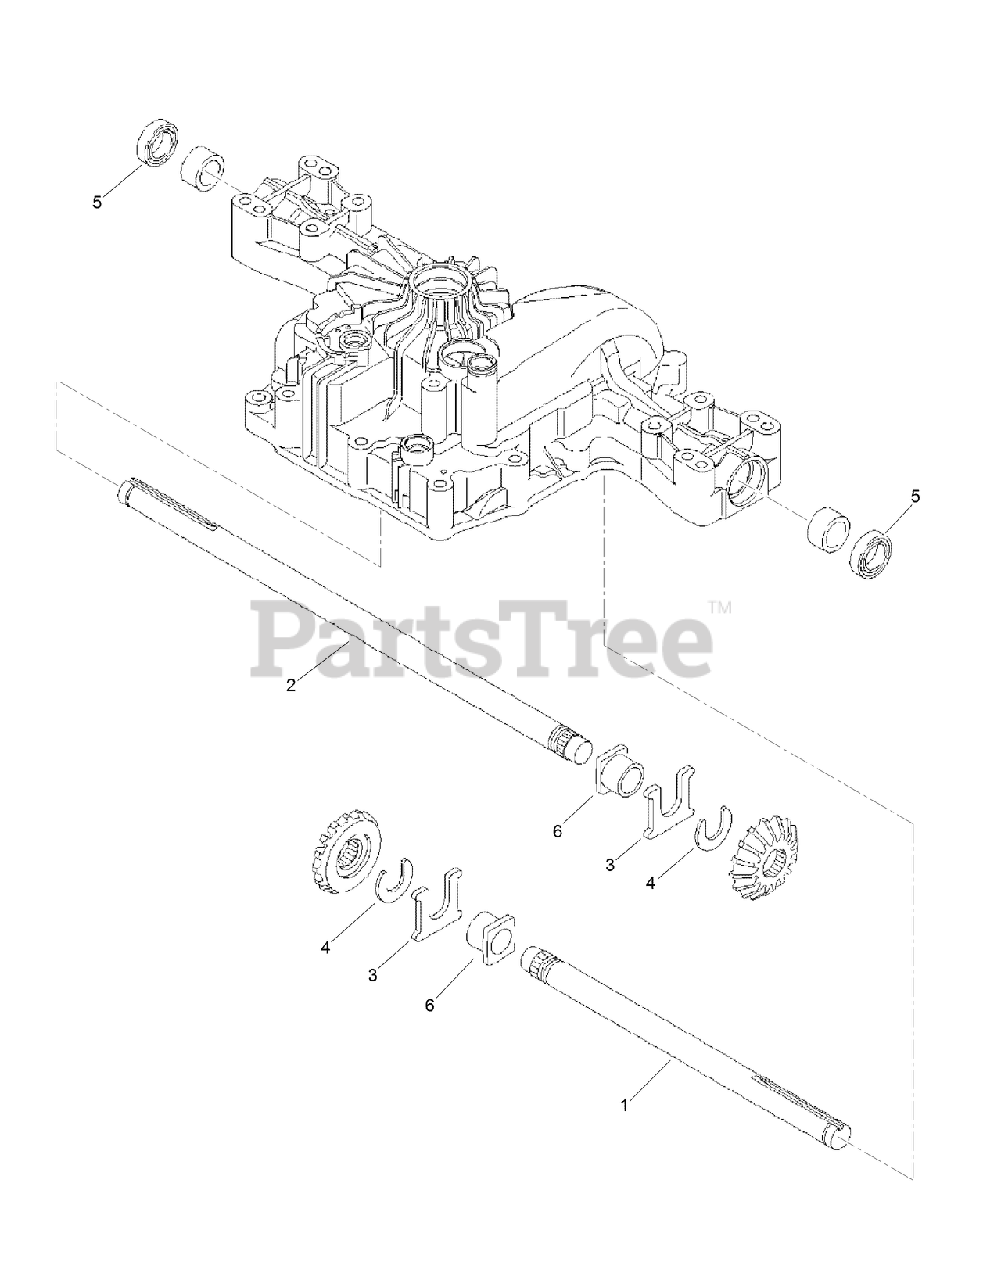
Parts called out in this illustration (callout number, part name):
1	SHAFT-AXLE, RH
2	SHAFT-AXLE, LH
3	WASHER-THRUST
6	BUSHING
